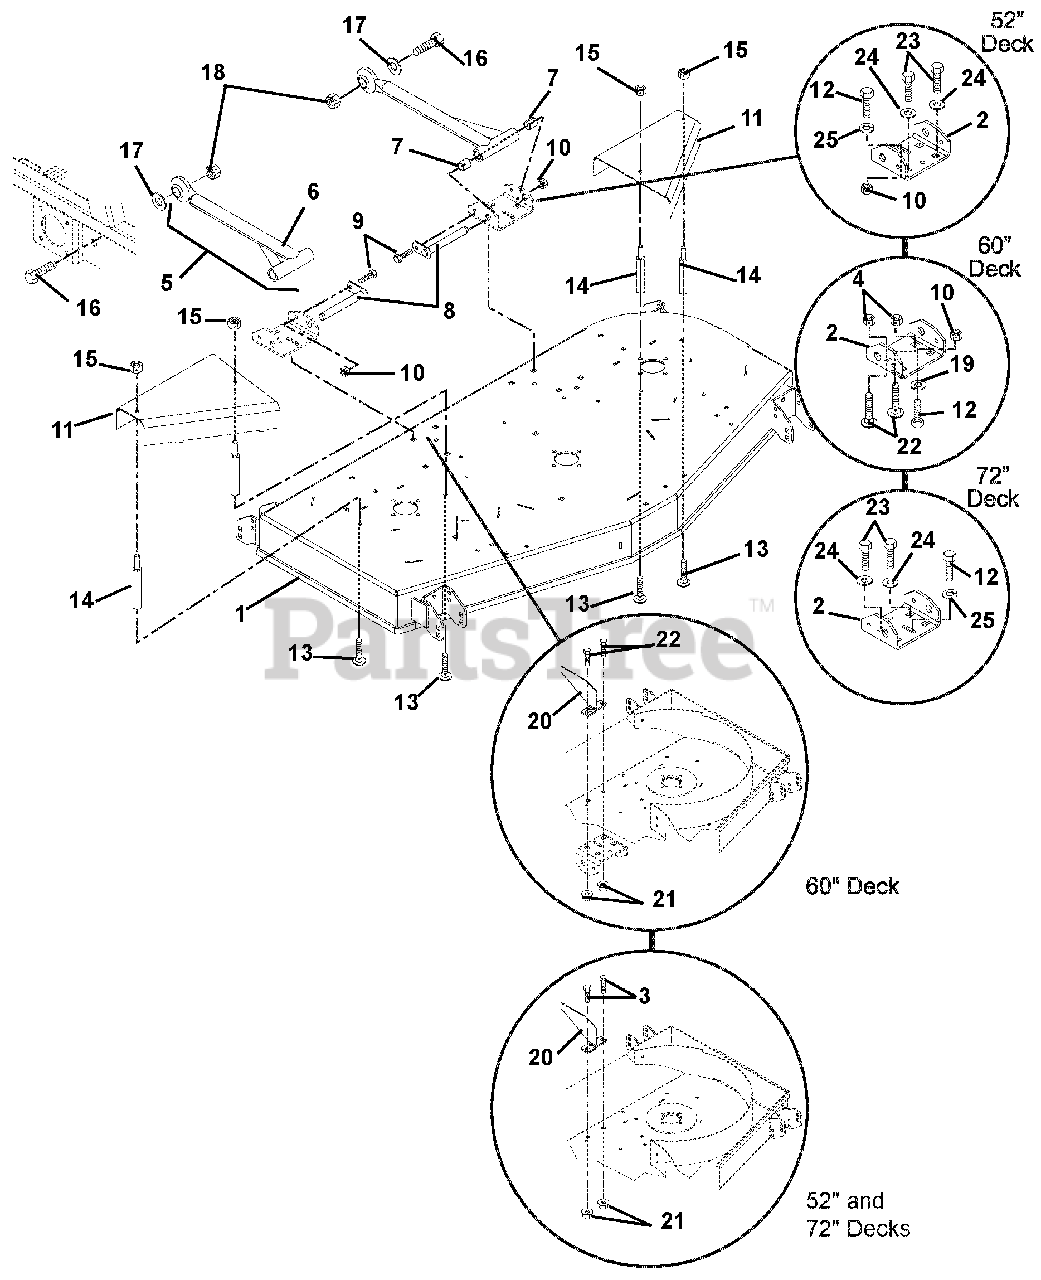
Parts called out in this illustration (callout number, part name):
1	Weldment, 52" Mower Deck Rear Discharge
2	Bracket, Mower Mounting (Rear)
3	Bolt, Round Head Square Neck .50-13 x .75 Grade 5 (316, 317)
4	Nut, Locking Center Jam .50-13 (316, 317)
5	Assembly, Mower Mounting Arm (Includes Items 6 and 7)
6	Weldment, Mower Mounting Arm
7	Bearing .75 x .875 x 1.00
8	Weldment, Mower Mounting Pin
9	Bolt, Hex .38-16 x .875 Grade 5
10	Nut, Locking Top Flange .38-16
11	Guard, Pulley Left Hand 60" (316, 317)
12	Bolt, Hex .38-16 x 1.00 Grade 5 (321, 322)
13	Bolt, Round Head Square Neck .31-18 x .75
14	Standoff 2.75 x 5/16-18
15	Nut, Locking Top Flange .31-18
16	Bolt, Hex .875-9 x 2.75 Grade 5
17	Washer, Flat Steel .875 x 1.50 x .120
18	Nut, Locking Center .875-9
19	Washer, Flat Steel .406 x .812 x .065 (316, 317)
20	Weldment, Rear Deflector Baffle
21	Nut, Locking Top Flange .50-13
22	Bolt, Round Head Square Neck .50-13 x 1.00 Grade 5 (316, 317)
23	Bolt, Hex .50-13 x 1.00 (321, 322)
24	Washer, Lock .50 x .125 (321, 322)
25	Washer, Lock .38 x .094 (321, 322)
